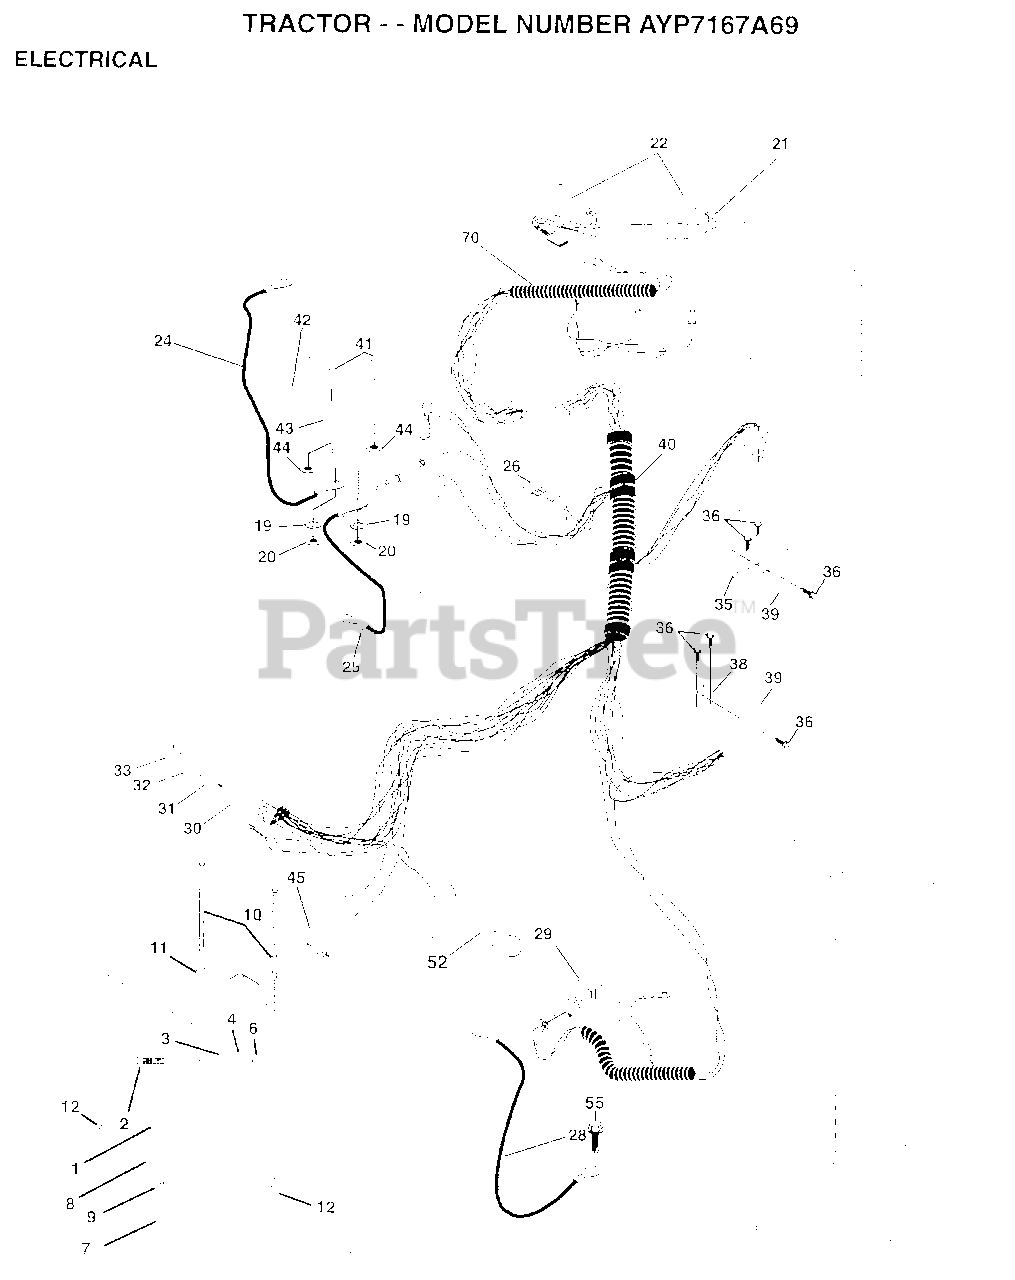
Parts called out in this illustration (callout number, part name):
2	BOLT LT
3	WASHER
4	LOCKWASHER
7	"DRAIN TU T, BATT"
8	"TRAY T, BATTERY"
9	HOSE CLAMP T
20	NUT
21	"HARNESS,LIGHT SOC"
22	HEADLAMP BULB
24	"CABLE T, BATTERY"
25	CABLE.6GA.22W/16W
26	FUSE HYT
28	CABLE.GRND.6GA.21
29	SWITCH SEAT
30	SWITCH IGN 4POS
31	NUT IGNITION
32	COVER KEY SWITCH
33	KEY
35	BRACKET LT
36	SCREW
38	BRACKET SWITCH IN
39	SWITCH INTERLOCKT
40	HARNESS.IGNITION
41	BOLT HXHD FIN
44	NUT HXKEP 1/4X20
45	AMMETER
52	PROTECTION LOOP
55	SCREW LT
70	HARNESS.ENG.LT.
